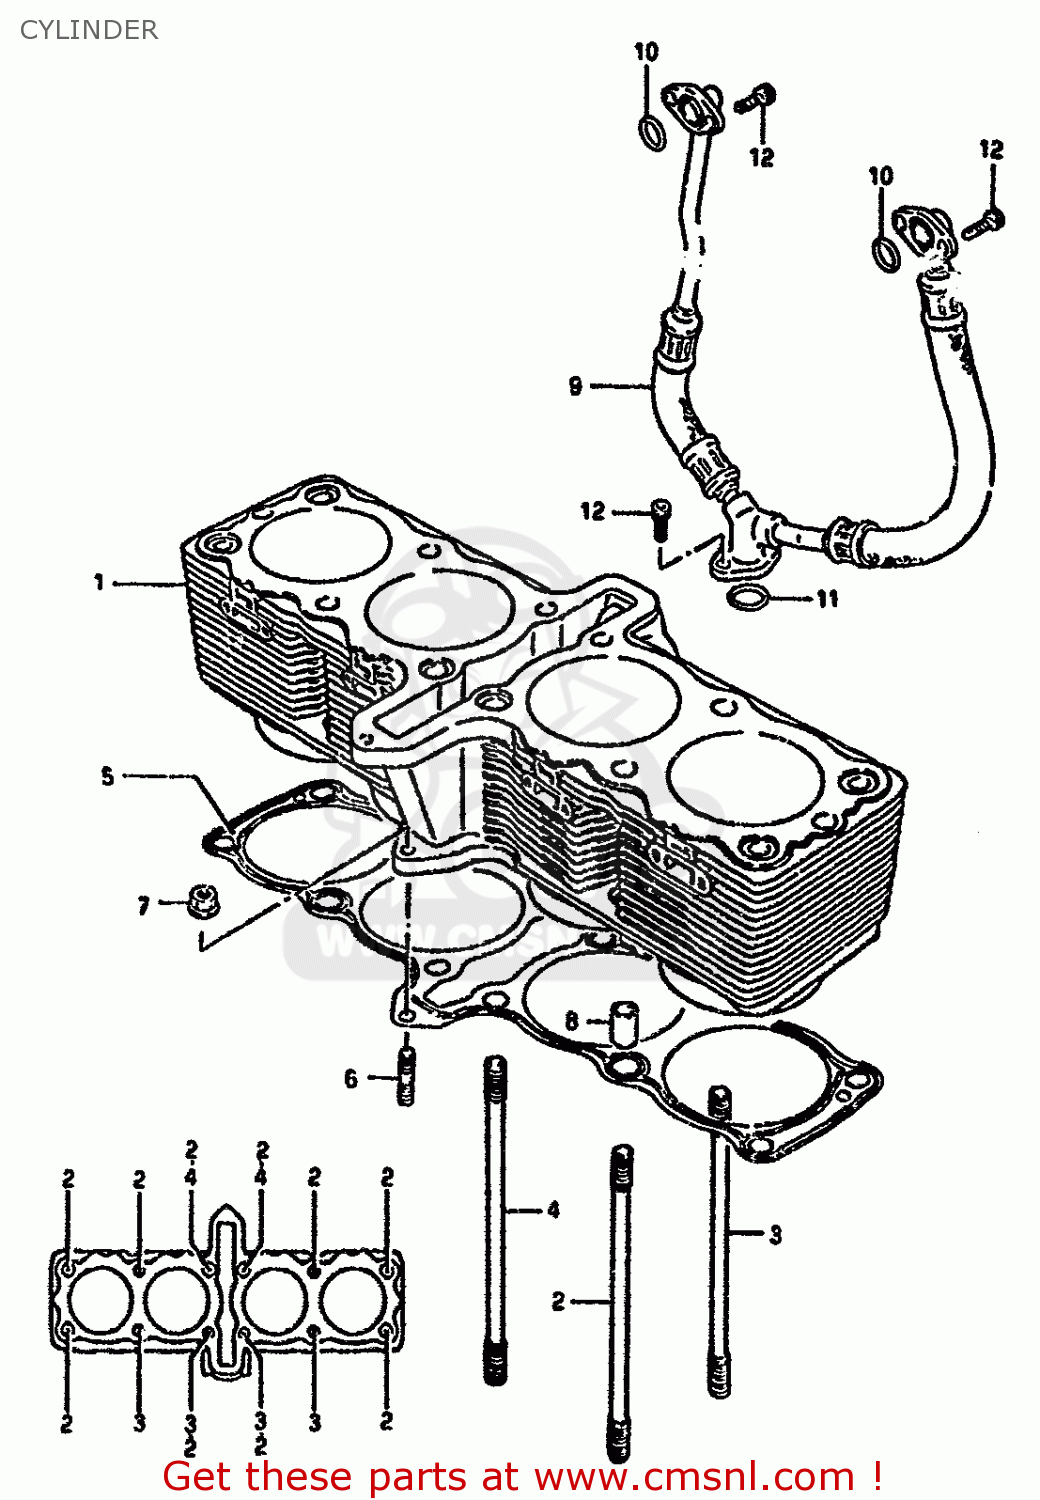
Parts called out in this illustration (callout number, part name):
1	CYLINDER
2	BOLT,STUD
3	BOLT,STUD
4	BOLT,STUD
5	GASKET,CYLINDER (NAS)
6	STUD BOLT L:20
7	NUT
8	PIN
9	HOSE
10	O RING(D:2.5,ID:13.8)
11	O RING(D:2.4,ID:15.8)
12	BOLT
